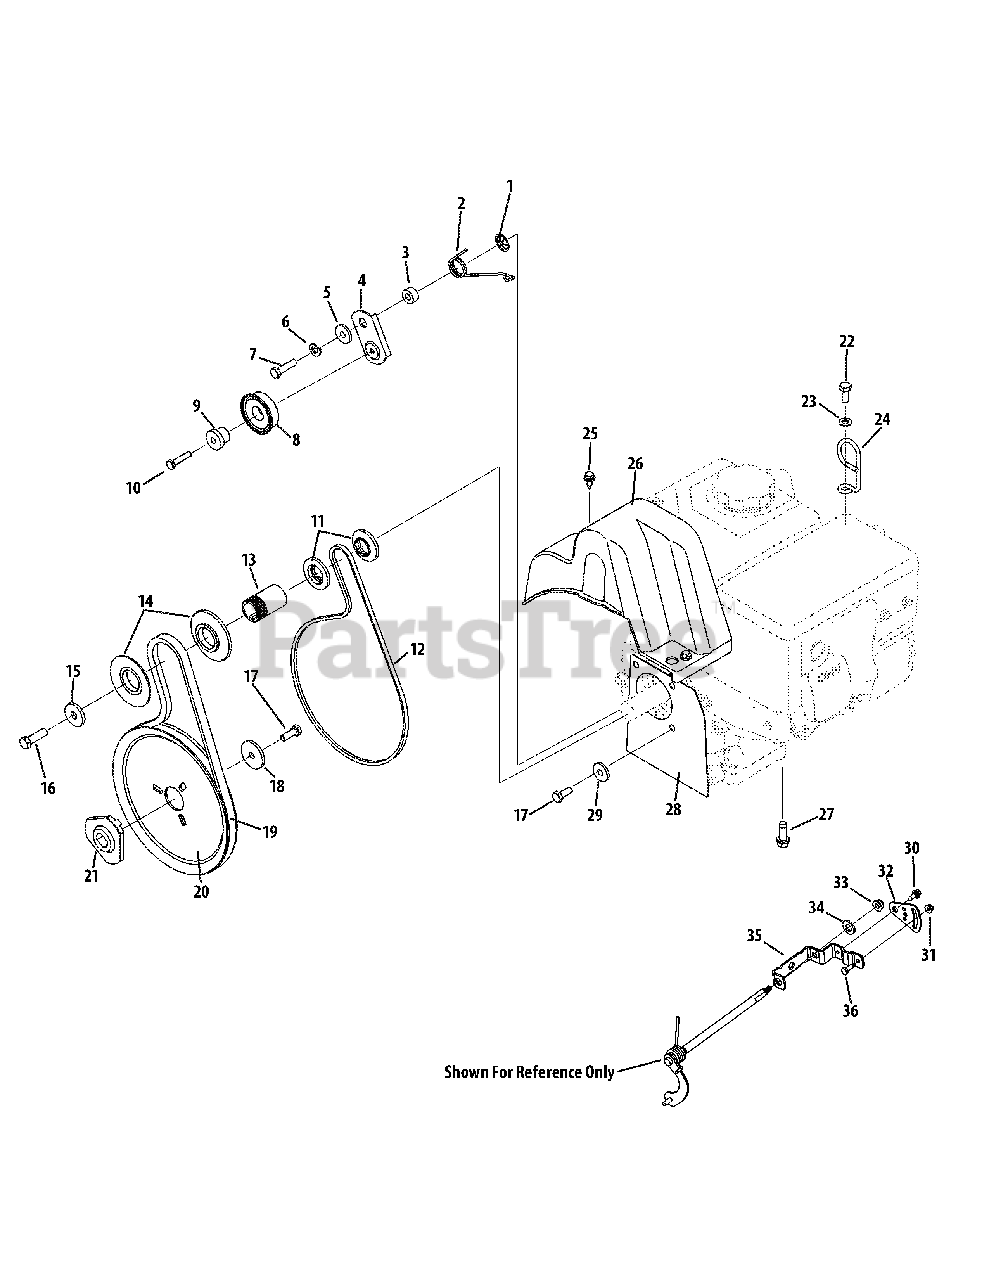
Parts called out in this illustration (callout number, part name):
1	Push-On Nut
2	Torsion Spring, .850 ID x .333
3	Spacer, .340 x .750 x .330
4	Idler Bracket
5	Shldr. Spacer, .3175 ID x .500 x .0975
6	Lock Washer, 5/16
7	Hex Screw, 5/16-24 x 1.25
8	Idler Pulley
9	Shoulder Spacer, .260 x .785 x .538
10	Hex Washer Screw, 1/4-20 x 1.250
11	Pulley Half, 3/8-V x 1.7160 OD
13	Spacer, .875 ID x 1.185 OD
14	Pulley Half, 4L-V x 2.600 OD
15	Flat Washer, .406 x 1.25 x .157
16	Hex Screw, 3/8-24 x 1.25
17	Hex Lock Screw, 5/16-24 x .875
18	Flat Washer, .34 x 1.50 x .150
19	Belt
20	Auger Pulley
21	Adapter Pulley
22	Hex Screw, M8-1.25 x 20
23	Flat Washer, .330 x .630 x .0635
24	Cable Control Wire
25	Hex Washer Screw, 1/4-20 x .375
26	Belt Cover
27	Hex Washer Screw, 3/8-16 x 1.250
28	Cover Plate
29	Shoulder Spacer
30	Shoulder Screw, .368 x .113 x 1/4-20
31	Flange Lock Nut, 1/4-20
32	Speed Selector Pivot Bracket
33	Flange Lock Nut,5/16-18
34	Flat Washer, .469 x .875 x .105
35	Speed Selector Shift Bracket
36	Hex Screw, 1/4-20 x .620
